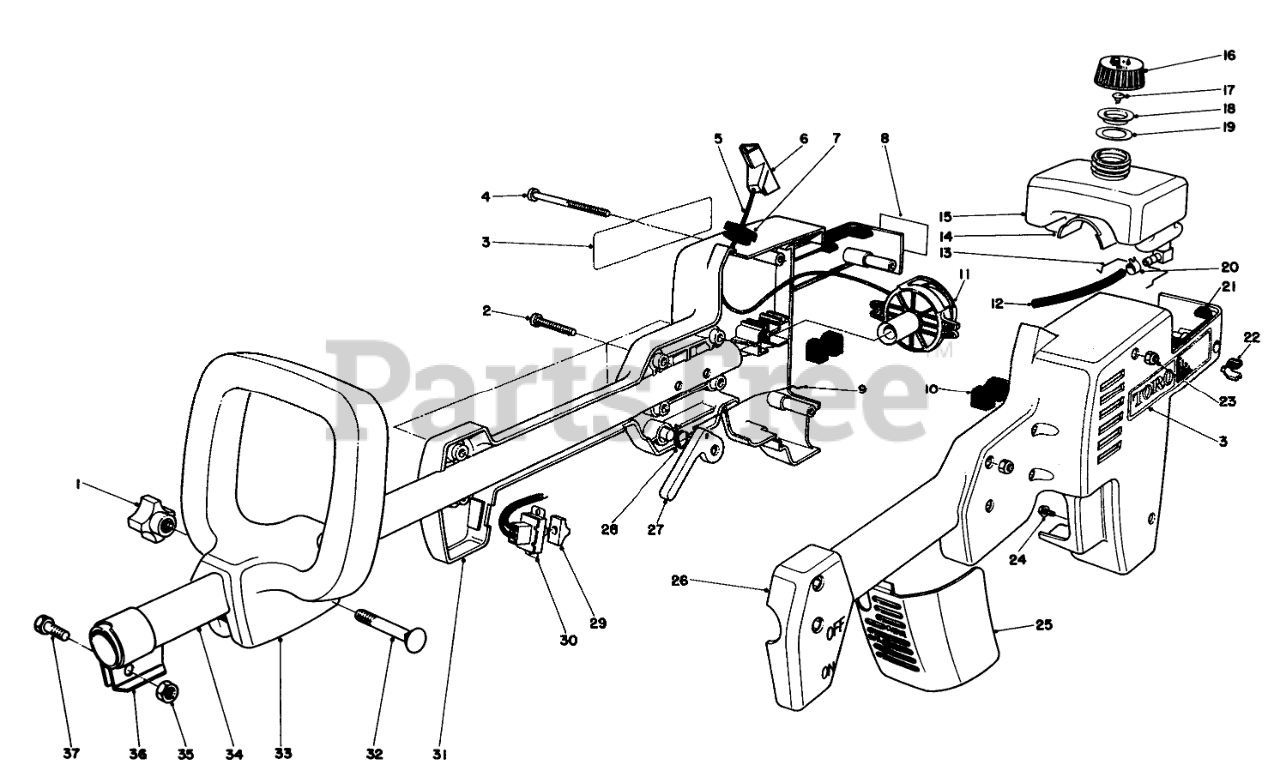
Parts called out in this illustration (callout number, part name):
1	Knob
2	Screw-Machine Cross Recess Pan Hd.
3	Decal
4	Screw-Machine Cross Recess Pan Hd.
5	Rope-Starter
6	Handle
7	Bushing Rope
8	Decal-Hot
9	Link-Throttle
10	Isolation Mount
11	Recoil Assy. (Incl. Ref. #5-7)
12	Gas Line
13	Clip-Crankcase Pad
14	Crankcase Pad
15	GAS TANK
16	Gas Cap Assy. (Incl. Ref. #17-19)
17	Valve
18	Insert
19	Gasket
20	CLAMP-HOSE
21	Bumper-Gas Tank
22	Grommet
23	NUT-LOCK, NI
24	10-16 X 3/8 THDG SCREW
25	Cover-Air Cleaner
26	Housing Engine L.H.
27	Lever Throttle
28	TORSION SPRING
29	SWITCH COVER-BLACK
30	SWITCH
31	Housing-Engine R.H. (Incl. Ref. #8)
32	BOLT-CARRIAGE
33	HANDLE SECONDARY
34	Tube-Upper Shaft
35	NUT-LOCK, NI
36	Clamp-Pole
37	SCREW-HH
